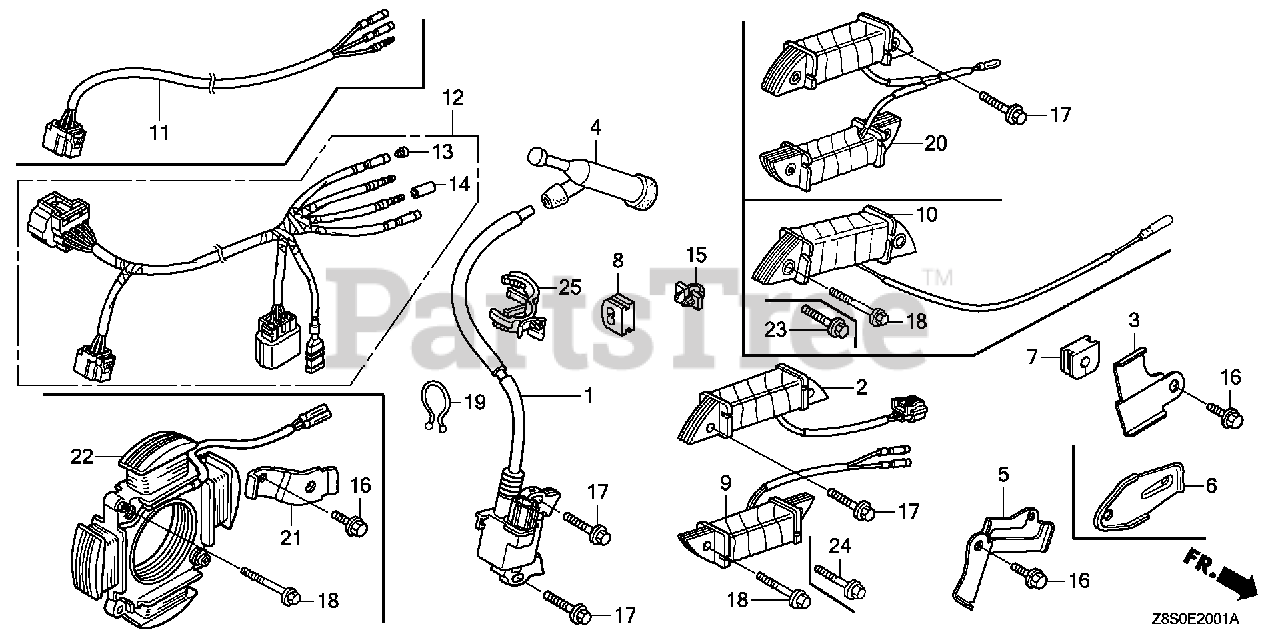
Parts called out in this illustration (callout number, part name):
1	COIL ASSY., IGNITION
4	CAP ASSY., NOISE SUPPRESSOR (NGK Y-EZD)
8	GROMMET, WIRE
11	WIRE HARNESS ASSY., ENGINE
17	BOLT, FLANGE (6X28) (CT200) Use up to Engine SN 1530314.
25	CLIP, WIRE HARNESS
